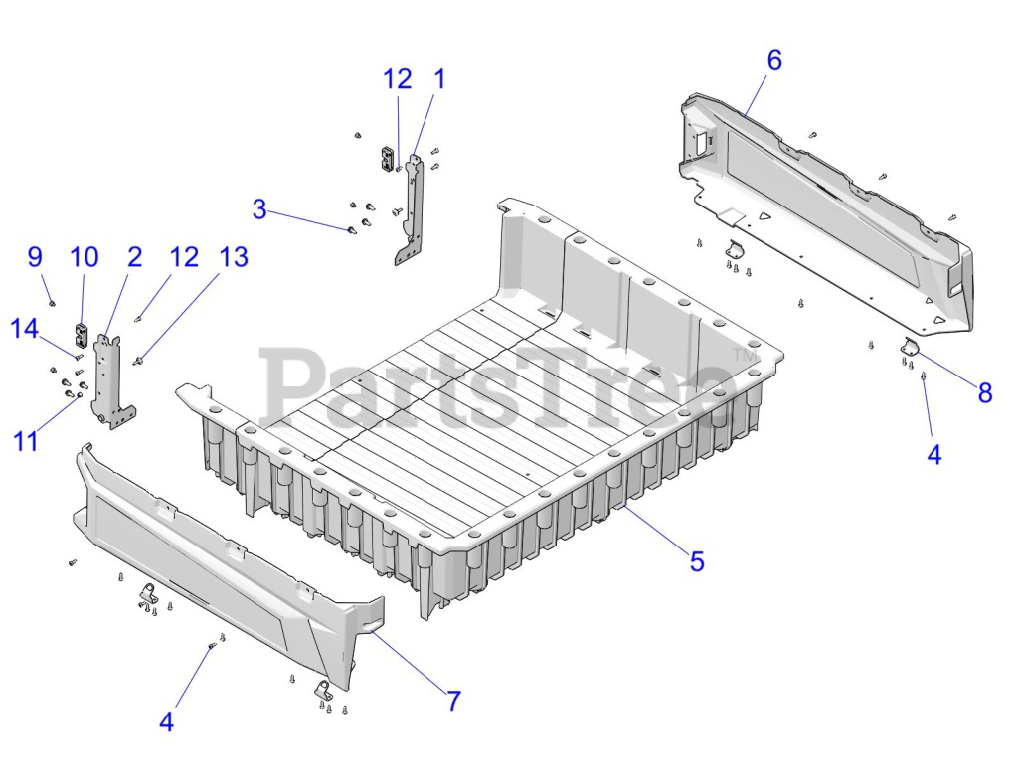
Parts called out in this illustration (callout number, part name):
1	WELD-TAILGATE SUPPORT-LH-BLK
2	WELD-TAILGATE SUPPORT-RH-BLK
3	BOLT-M8X1.25X20-HXFLG-TAP/R-OD
4	SCR-TXPH-#14 X .75 HI-LO RIE
5	K-BOX- LONG- ARNS- BLK
6	PANEL-BOX-LONG-LH-BLK
7	PANEL-BOX-LONG-RH-BLK
8	BRKT-BOX- TIE DOWN
9	BUMPER-RUBBER-13.50 DIAX4.3THK
10	LATCH-SLAM-TAILGATE
11	NUT-M6 FLANGE-NYLOK
12	SCR-TX TRUSS-#14X3/4-HI/LO ZBK
13	SCR-TXTH-M6X1.0X25 RIE-SHDR
14	SCR-#14X3/4 HI/LO-PH-PN TRX-M
